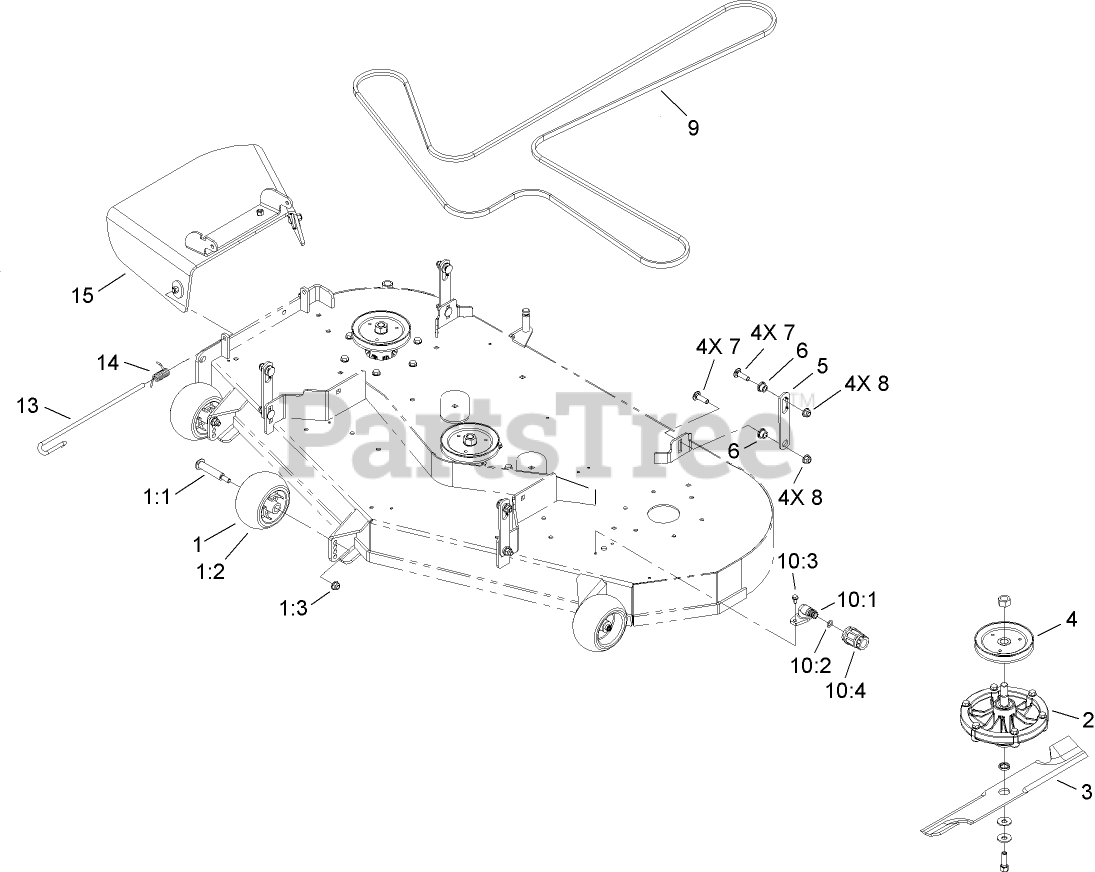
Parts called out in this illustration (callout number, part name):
1	ANTI-SCALP ROLLER KIT
1:1	BOLT-SHOULDER
1:2	ROLLER-SCALP, ANTI
1:3	NUT-HF, NI
3	BLADE-NOTCHED
5	HANGER-DECK
6	SPACER-STRUT
7	BOLT-CARR
8	NUT-HF, NI
9	BELT
10:2	O-RING
10:3	SCREW-HWH
10:4	CONNECTOR-HOSE
14	SPRING
15	RUBBER DEFLECTOR ASM
